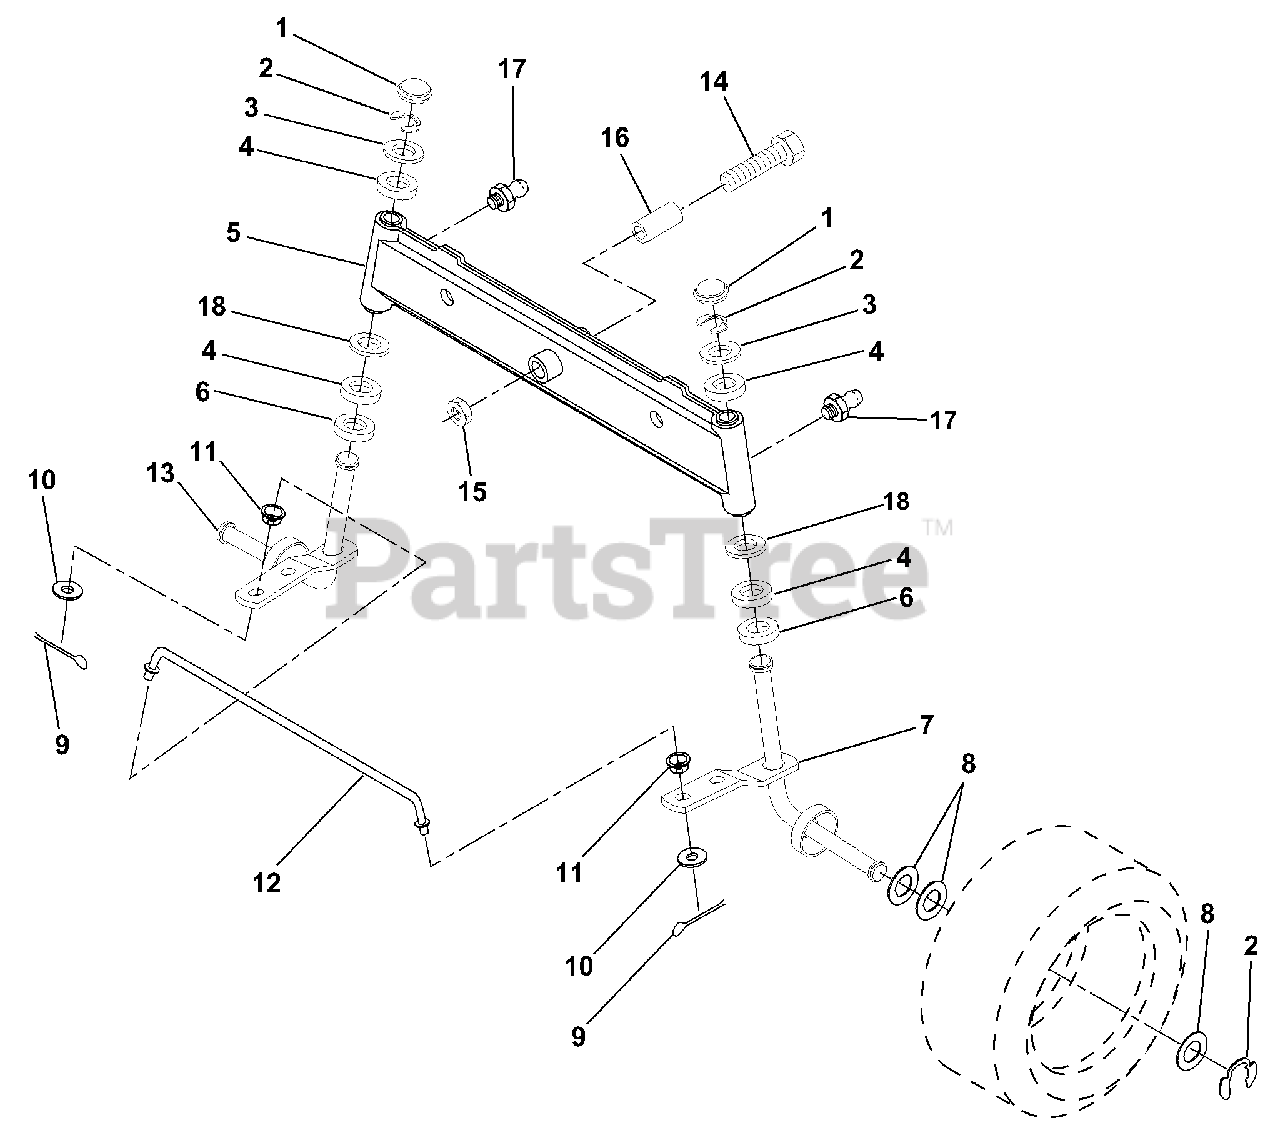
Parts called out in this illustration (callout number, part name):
1	Cap, Spindle
2	Ring, Clip
3	Washer 25/32 x 1-5/8 x 16 Ga.
4	Nyliner
5	Axle, Front
6	Bearing, Thrust
7	Spindle, R.H. Asm.
8	Washer 25/32 x 1-1/4 x 16 Ga.
9	Pin, Cotter 1/8 x 3/4
10	Washer 13/32 x 13/16 x 16 Ga.
12	Rod, Tie
13	Spindle, L.H. Asm.
14	Bolt Hex 5/1-11 x 3-1/2
15	Nut, Lock Flange 5/8-11
16	Spacer, Bearing Axle
17	Fitting, Grease
18	Washer 27/32 x 1-1/4 x 16 Ga.
